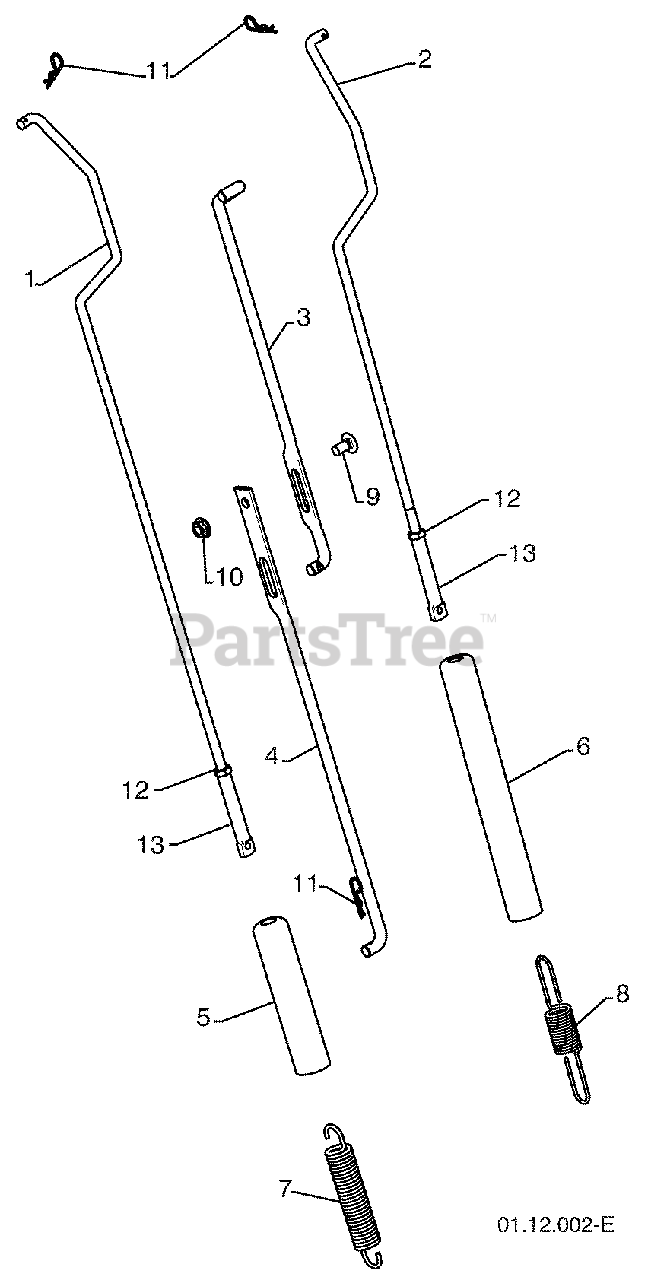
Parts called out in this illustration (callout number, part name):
1	IMPELLER ROD ASSEMBLY
2	TRACTION ROD ASSEMBLY
3	SHIFTER ROD TOP
4	SHIFTER ROD BOTTOM
5	SPRING SLEEVE
6	SPRING SLEEVE
7	IMPELLER SPRING
8	TRACTION SPRING
9	CARRIAGE BOLT 5/16-18 X .750
10	NUT 5/16-18
12	5/16-18 JAM NUT
13	CONTROL ROD END
